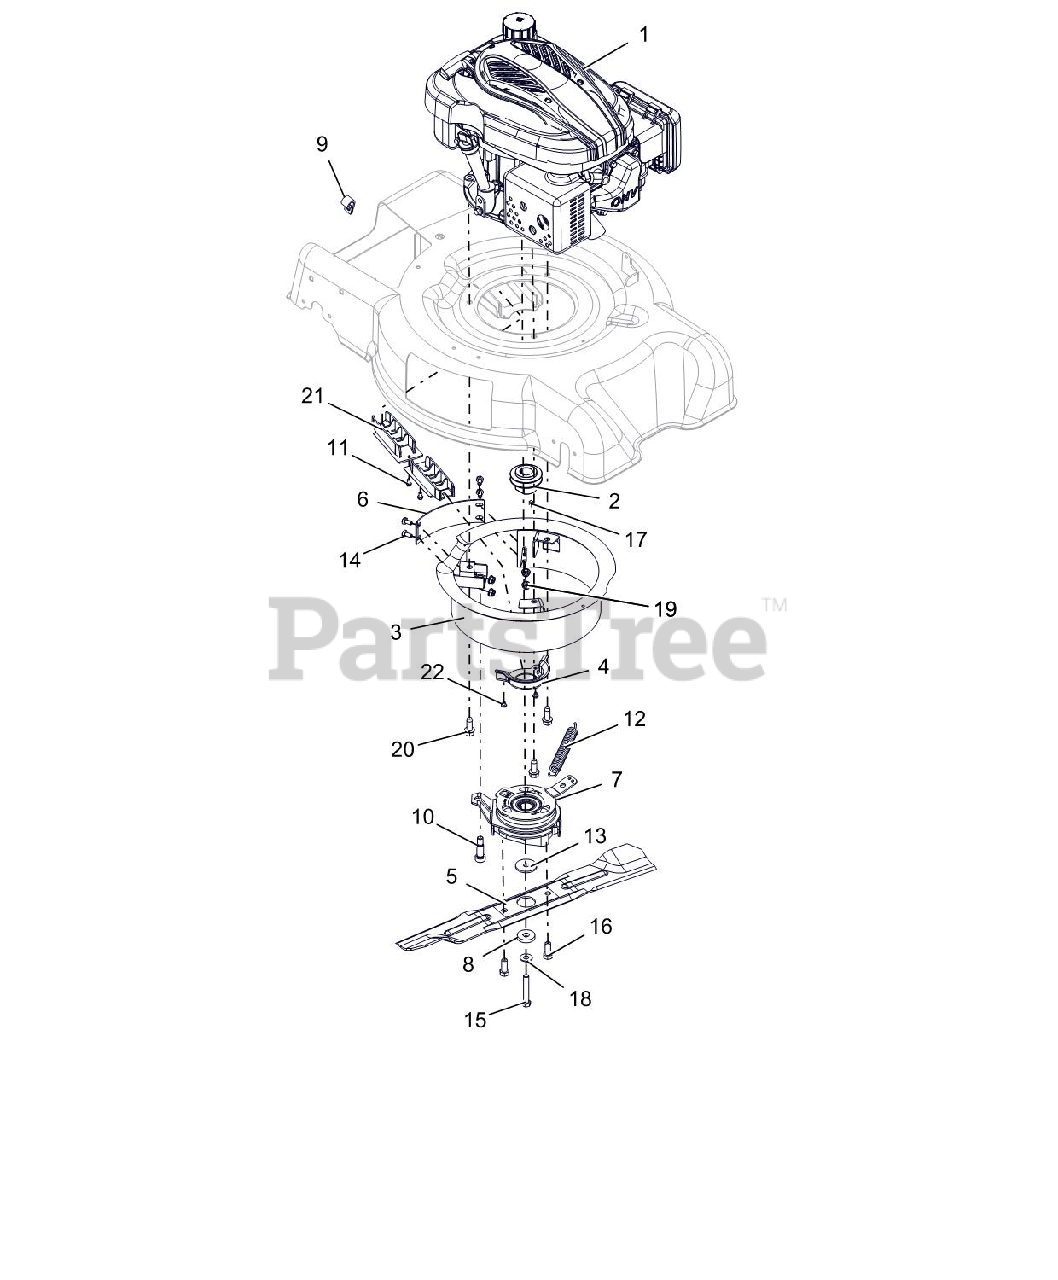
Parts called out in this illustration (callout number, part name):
1	ENGINE, LONCIN 159CC VERT. BBC
2	PULLEY, 7/8 MACHINED LM DRIVE
3	WLDMT, ENCLOSURE - BBC
4	GUIDE, BELT CRANK
5	BLADE, MOWER 21" HIGH LIFT-BBC
6	BAFFLE, BBC
7	CLUTCH, RAZOR/XD3, 7/8"
8	WSHR-FL-STL .44X1.25X.25 YWZC
9	CLAMP, LM CABLE
10	BLT,SHLDR 12MM X 25 W/ M10 THD
11	SCR-TAP 10-24X.375 PRE-COAT 80
12	SPRING, EXTENSION BBC
13	WSHR-FL-STL .380X1.50X.125YWZC
14	@BLT-HEX .25-20X.50 GR5 YWZC
15	BLT-HEX 3/8-24 X2.25 GR8
16	BLT-HEX M10 X 1.5X25 YWZC
17	KEY-SQ .188X.188X.375
18	WSHR-HDND .375X.875X.064 YWZC
19	@NUT-LK-TOP-FLG .25-20 YWZC
20	@SCR-TAP .38-16X1.00 HWH TR YZ
21	GUIDE, BELT INNER
22	SCR-TAP 10-24X.25 CRSLPH TR YZ
